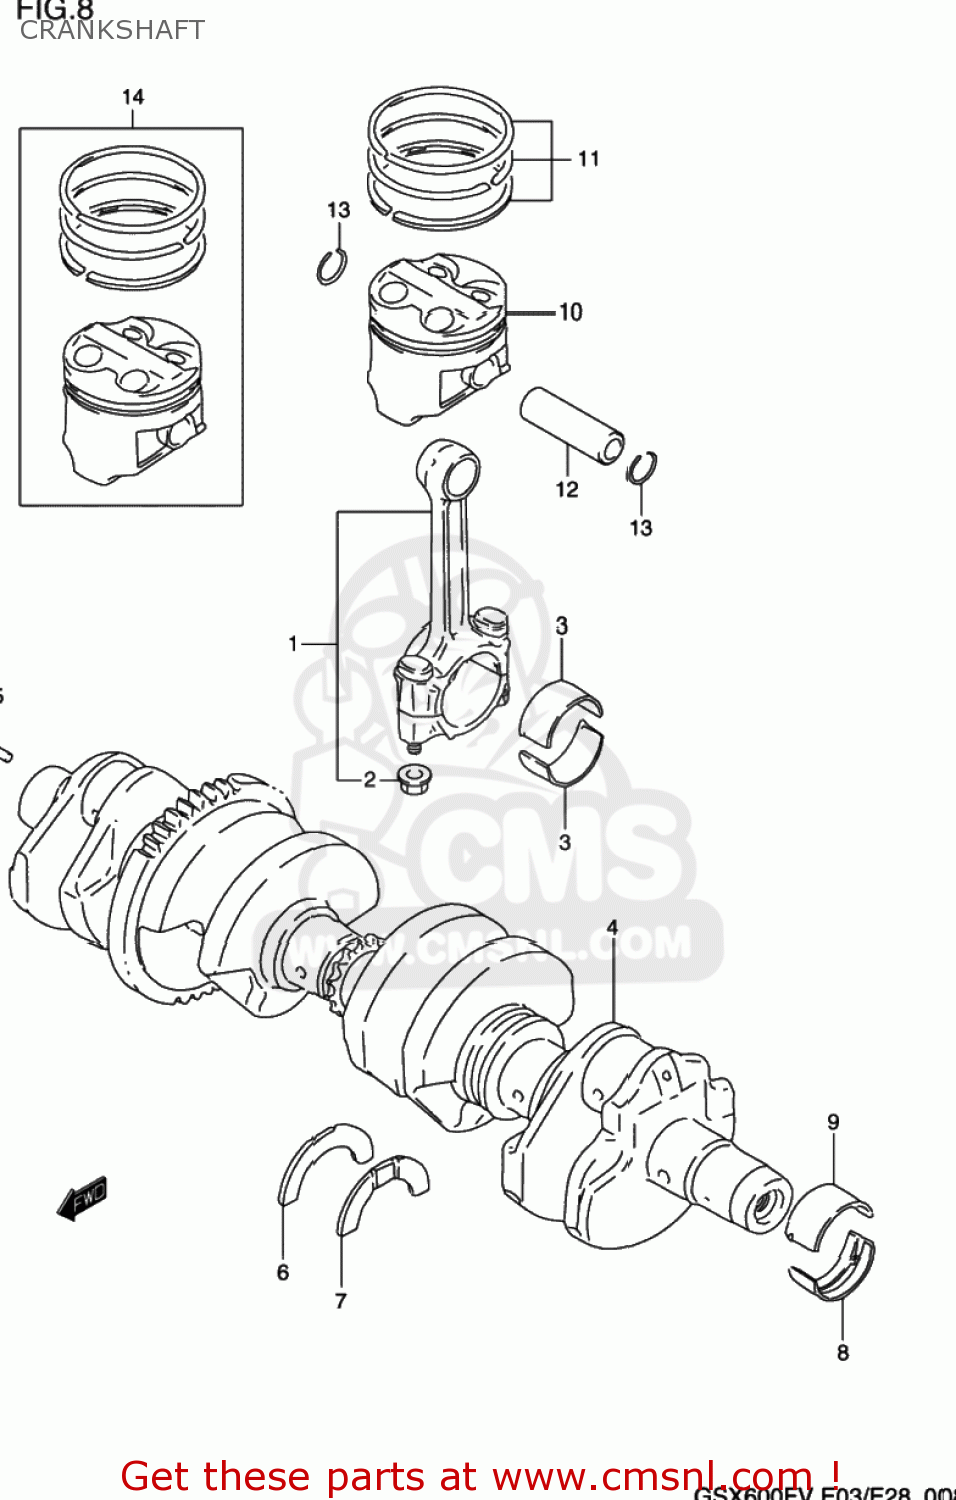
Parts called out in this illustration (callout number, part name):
1	ROD ASSEMBLY,CONNECTING
2	NUT
3	BEARING,CRANK PIN
4	CRANKSHAFT SET
5	PIN
6	PLATE,CRANK THRUST
7	PLATE,CRANK THRUST
8	BEARING,CRANKSHAFT LWR
9	BEARING,CRANKSHAFT UPR
10	PISTON
11	RING SET,PISTON
12	PIN,PISTON
13	CIRCLIP
14	PISTON SET(OS:0.5)
